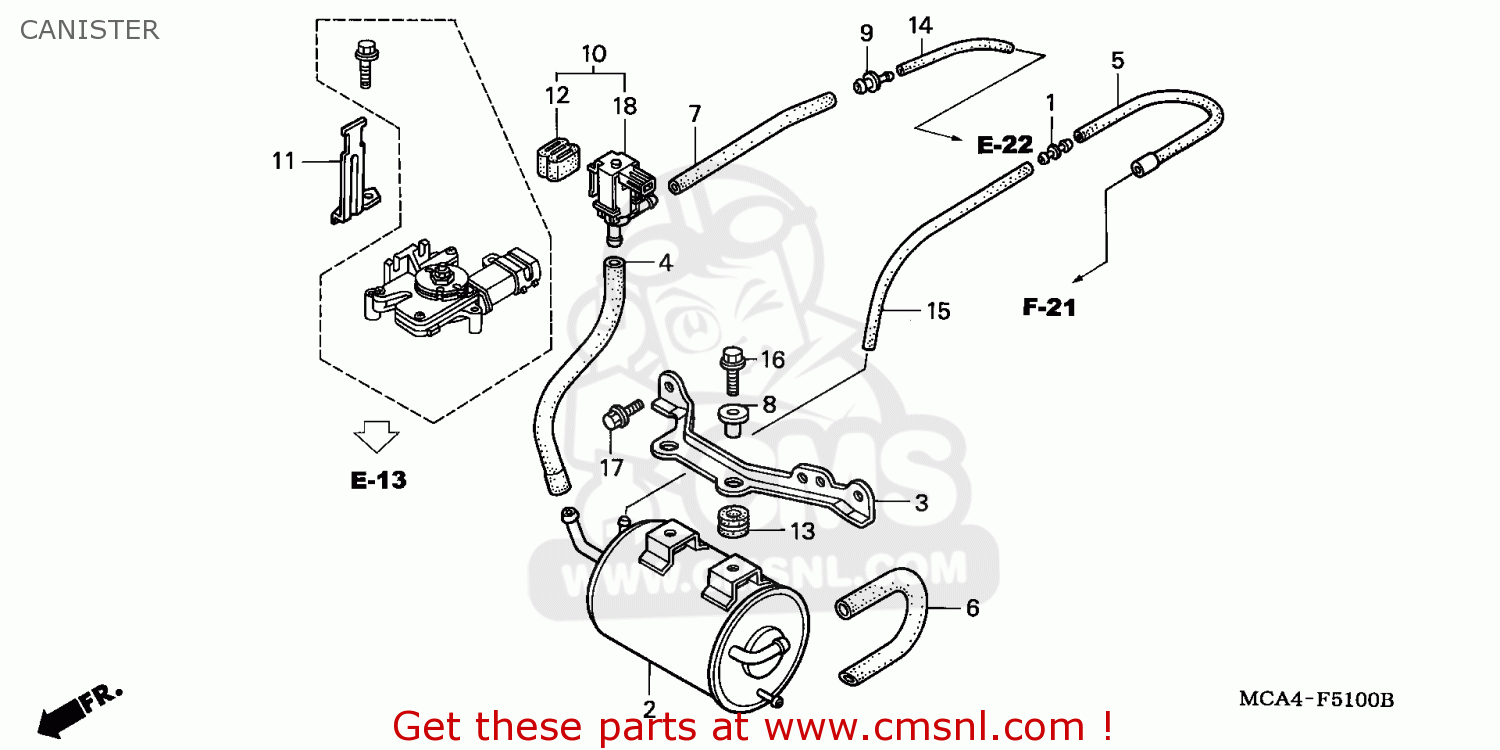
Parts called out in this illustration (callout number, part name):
1	JOINT,FUEL TUBE
2	CANISTER COMP
3	STAY,CANISTER
4	TUBE,PCS-CANISTER
5	TUBE A,AIR BREATH
6	TUBE B,AIR BREATH
7	TUBE C,AIR BREATH
8	COLLAR TANK SET.
9	JOINT,TUBE
10	VLV ASSY,PURGE CO
11	STAY,P.C.S
12	RUBBER,MOUNT
13	RUBB CONTROL BOX
14	TUBE,3.5X120
15	TUBE,4.5X860
17	BOLT,FLANGE,SH,6X14
18	SOL VLV,PURGE CON
